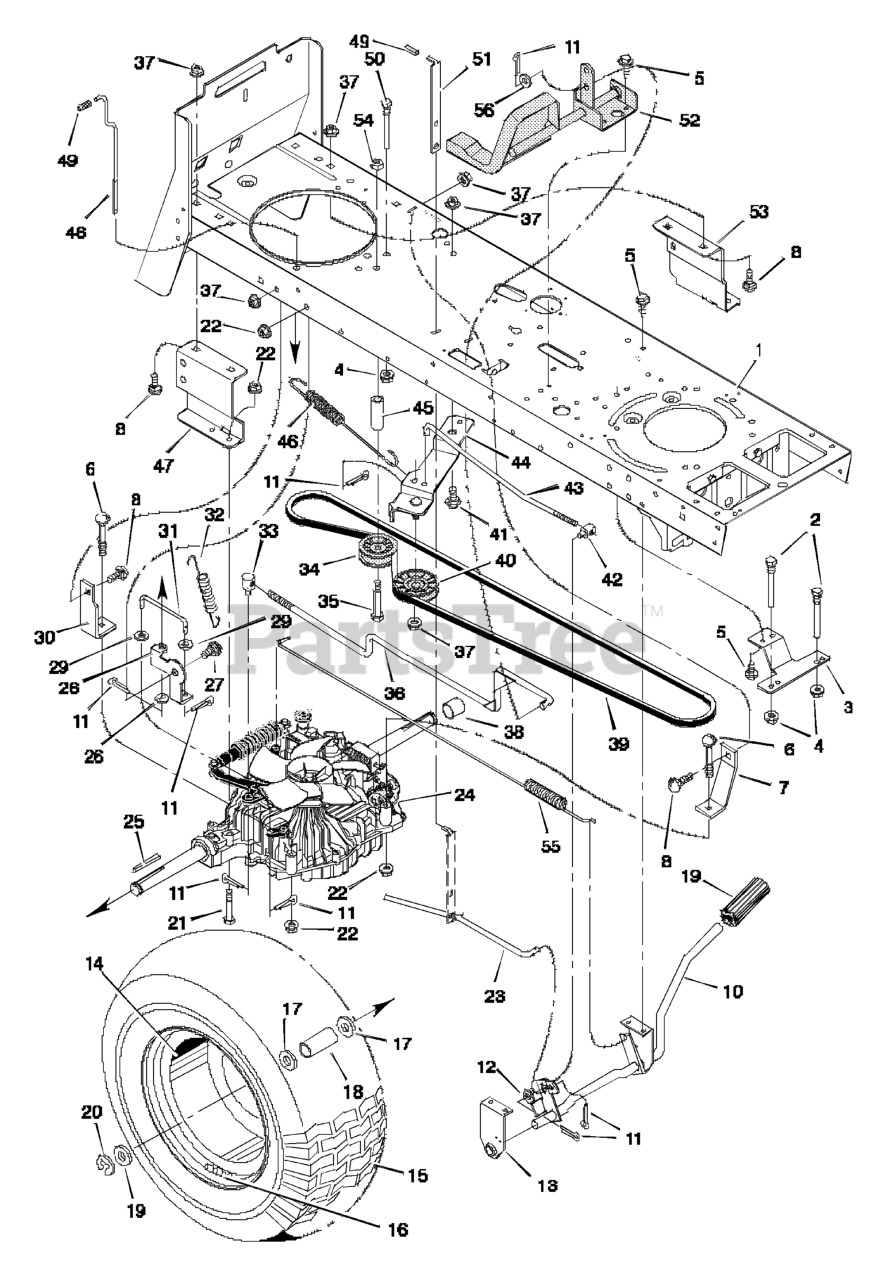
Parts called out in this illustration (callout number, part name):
1	Frame Assembly
2	Guide, Belt
3	Bracket, Belt Guide
4	Nut, Flange
6	Bolt, Carriage
7	Bracket, Torque
8	Bolt, Carriage
9	Pedal
10	Lever Assembly, Pedal
11	Pin, Cotter
12	Washer
13	Support, Pedal
14	Wheel and Tire Assembly
15	Tire *
16	Valve Stem
17	Washer
18	Spacer
19	WASHER, 1-1.3 16G FLT
20	E- Ring
21	Bolt, Hex
22	Nut
23	Rod, Latch
24	Transaxle
25	Key, Square
27	Bolt, Shoulder
28	Bracket, Dump Valve
29	Washer
30	Bracket, Torque
31	Rod, Dump Valve
32	Spring, Extension
33	NUT, Adjusting, 1/2-13
34	Pulley, Idler
35	Bolt, Hex
36	Rod, Control
37	Nut
38	Spacer
40	Pulley, Idler
41	Bolt, Shoulder
42	Nut, Adjusting
43	Rod, Clutch
44	Bracket, Idler
45	Spacer
46	Spring, Extension
47	Bracket, Right Transaxle
48	Rod, Dump Valve
50	Guide, Belt
51	Lever, Parking Brake
52	Pedal Assembly
53	Bracket, Left Transaxle
